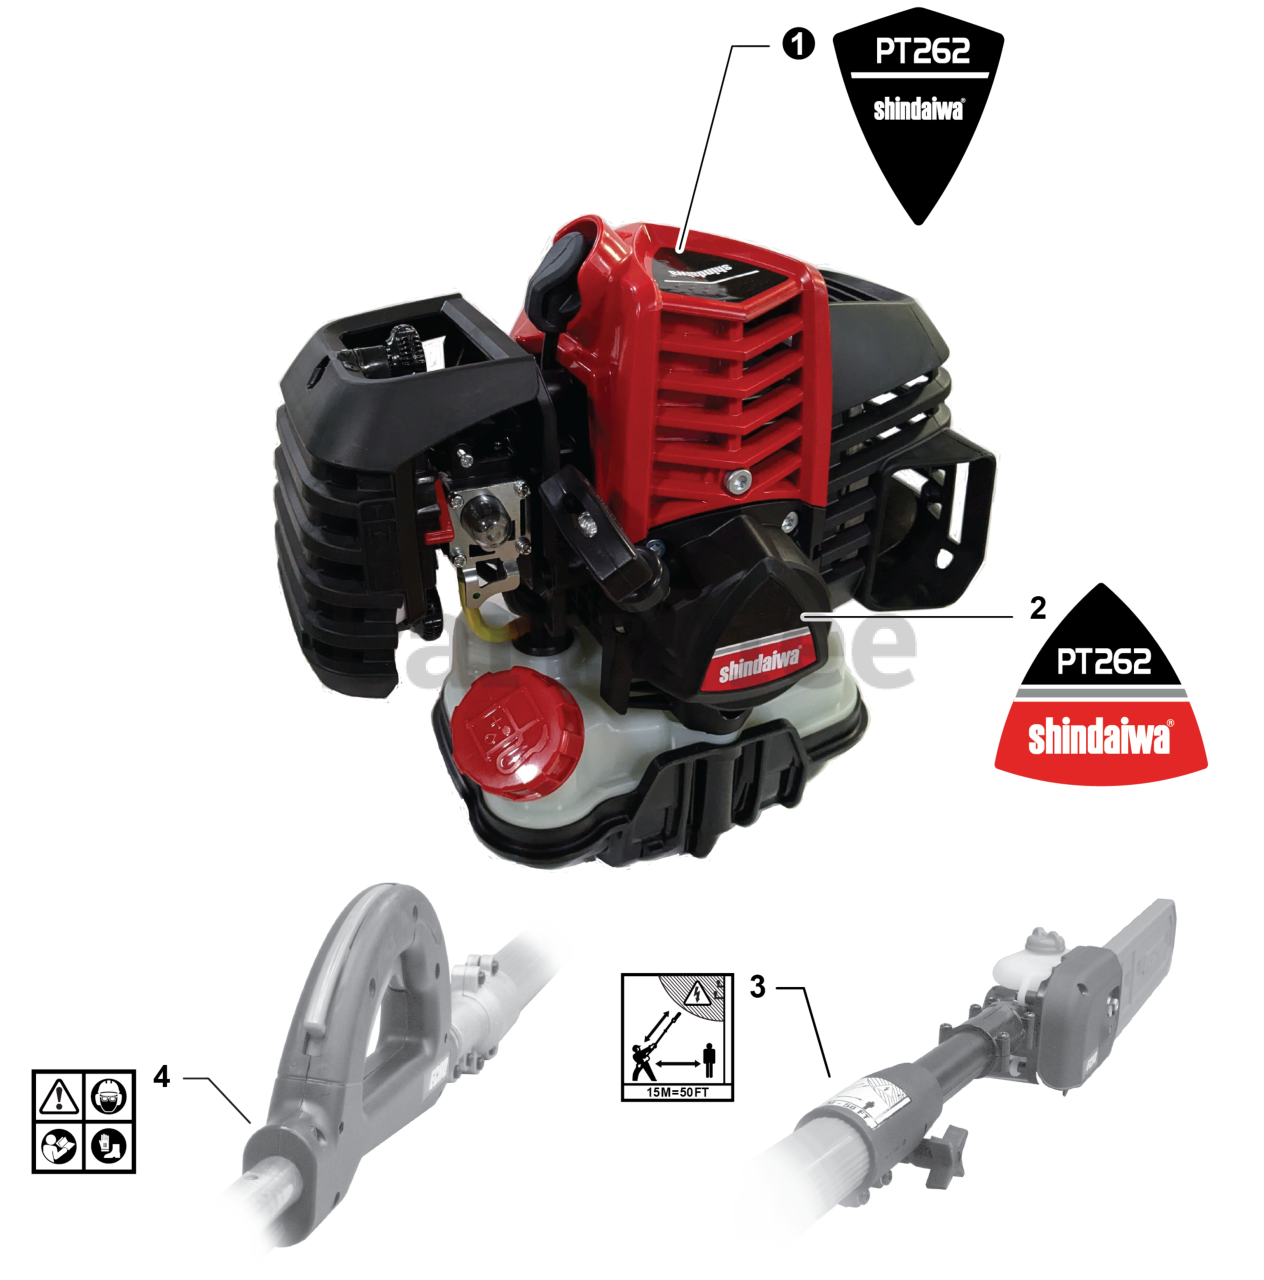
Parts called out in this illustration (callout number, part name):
1	LABEL - MODEL PT262
2	LABEL - RECOIL STARTER - PT262
3	LABEL - CAUTION
4	LABEL - CAUTION - ISO
